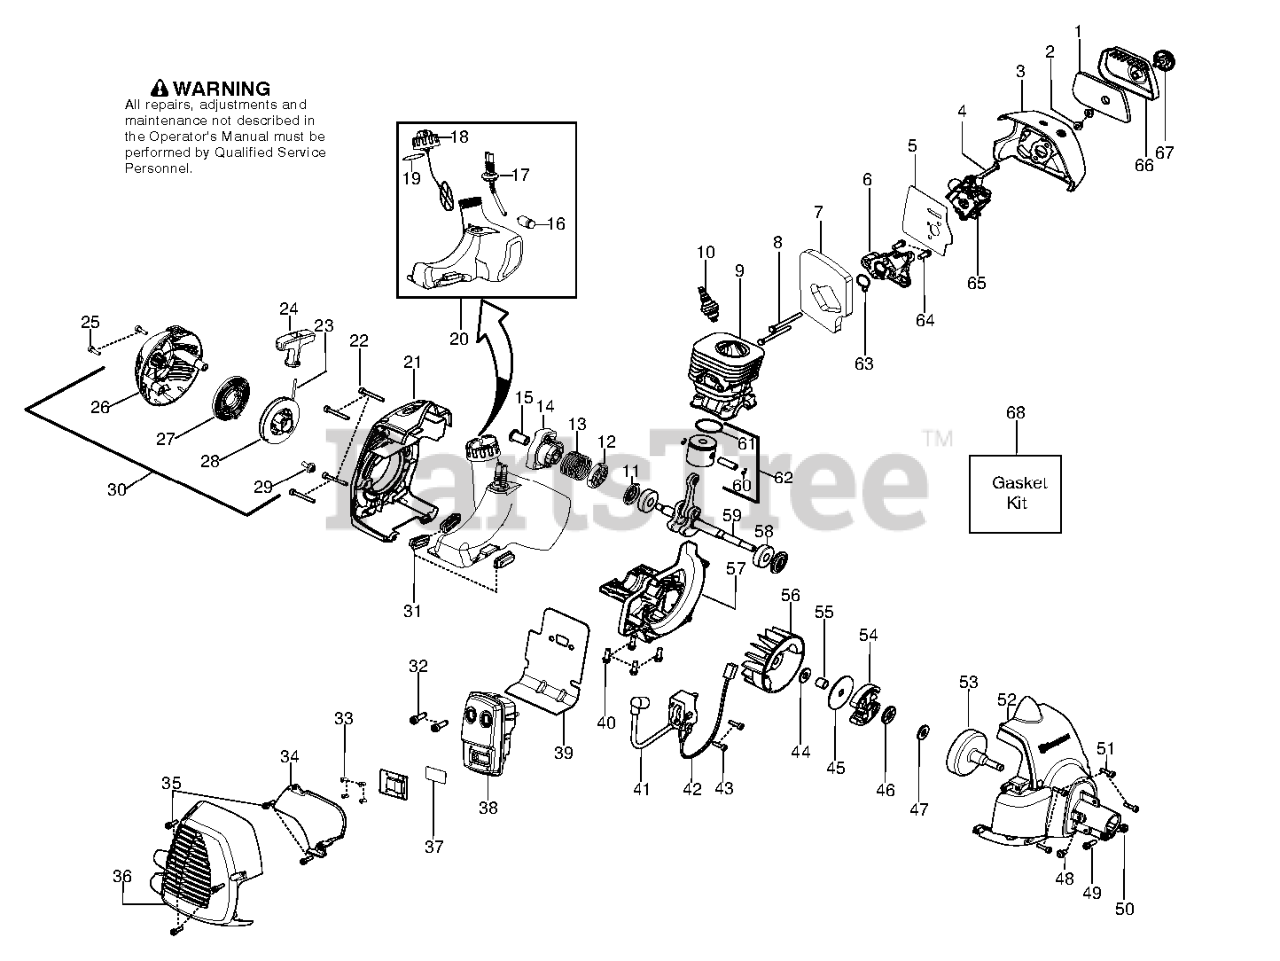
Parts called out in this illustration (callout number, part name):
3	RP_AIR BOX
4	CHOKE LEVER
5	KIT GASKET CARB
6	CARB ADAPTOR
7	KIT GASKET 28CC
8	BOLT CARB ADAPTOR
9	CYLINDER
10	Plug - Spark (RCJ-8Y)
11	KIT SEAL CRANKSHAFT
12	WASHER STARTER
13	SPRING STARTER CUP
14	ASSY STARTER CUP
15	COUPLING STARTER
16	FUEL PICK-UP ASSY
17	KIT FUEL LINE
18	ASSY-CAP W/RETAINER
19	KIT GASKET 28CC
20	ASSY FUEL TANK HVA
21	REAR SHROUD
24	STARTER HANDLE GRAY
25	SCREW M5-0.8X30MM
26	CRANKCASE 28CC MACHINED
27	%KIT STARTER SPRING
28	KIT STARTER PULLEY
30	ASSY-STARTER HSG.
31	ISOLATOR FUEL TANK
32	BOLT MUFFLER
33	SCREW-10-16 X 1/2 HI-LO
34	SHIELD HEAT
35	SCREW M4 X 1.75 PT 16MM
36	GUARD-MUFFLER
37	KIT SPARK ARRESTOR SCREEN
38	ASSY MUFFLER NC
39	KIT GASKET 28CC
40	SCREW-M5-0.8 X 25MM(TAP)
41	IGNITION MODULE MBU-7
42	ASSY MODULE LEAD WIRE
43	SCREW M4 X .70 TT 16MM
44	WASHER CLUTCH
45	WASHER-CLUTCH
46	BEARING THRUST
47	WASHER THRUST
50	LOCKNUT-HEX 10-24
51	SCREW M4 X .70 TT 16MM
52	FAN HSG ASSY
53	ASSY-CLUTCH DRUM
54	%KIT CLUTCH ASSY
55	SPACER FLYWHEEL
57	CRANKCASE CASTING
58	BEARING RADIAL BALL (6201)
59	KIT CRANKSHAFT ASSY
60	WRIST PIN RET.
61	RING PISTON
62	KIT PISTON 28CC TRIMMER
63	KIT GASKET 28CC
64	SCREW-M5-0.8 X 25MM(TAP)
65	KIT - CARBURETOR
66	COVER-AIR BOX
67	KNOB ASSY AIRBOX COVER
68	KIT GASKET 28CC
